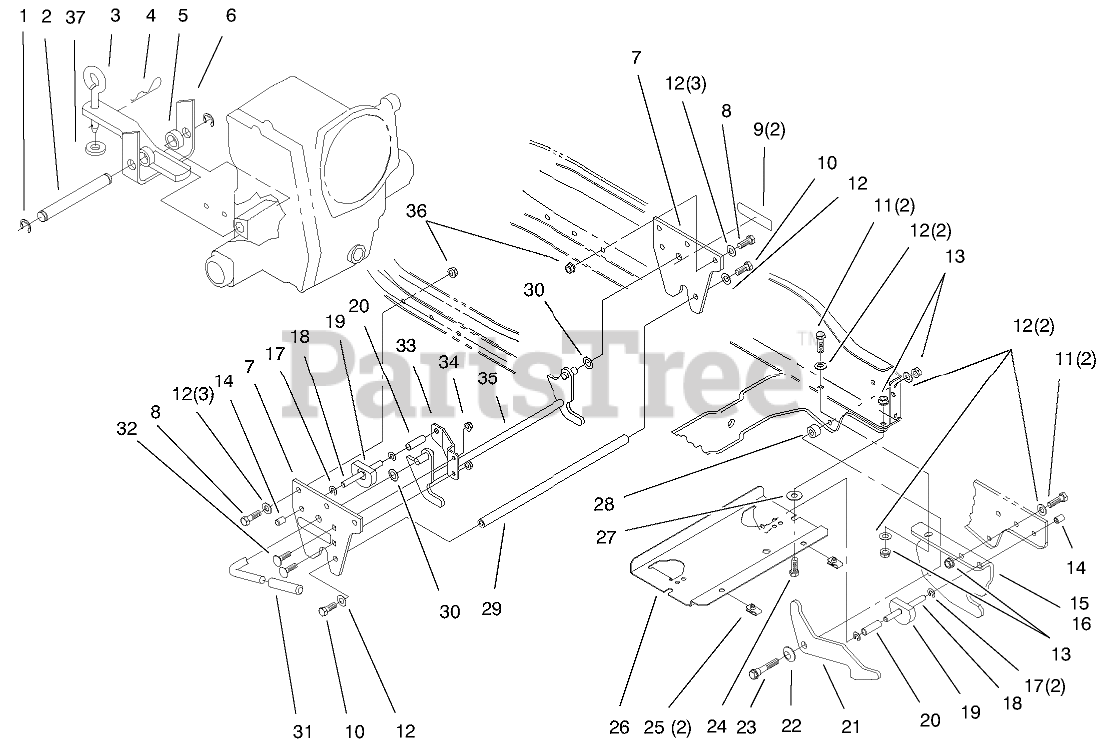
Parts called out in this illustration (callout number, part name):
1	E-RING
2	PIN-STATIONARY HITCH
3	PIN-TOOL
4	PIN-HAIR
5	SPACER
6	Hitch ASM
7	PLATE-HITCH
8	SCREW-HH
9	DECAL-ATTACH A MATIC
10	SCREW-HH, LOCK
11	SCREW-HH
12	WASHER-FLAT
13	NUT-LOCK, NI
14	CAP-ROD, PLUNGER
16	HANGER-LH
17	RING-RETAINING
18	ROD-LOCK
19	LOCK-LATCH
20	SPRING
21	Latch-Pulley Box
22	WASHER-SPRING
23	BOLT-SHOULDER
24	SCREW-HH
26	TRAY-BATTERY
27	WASHER-TOP THRUST
28	SPACER
29	ROD-SPACER
30	WASHER
31	GRIP
32	BOLT-CARR
33	BRACKET-ARM, MID
34	NUT-LOCK, NI
37	WASHER-FLAT
